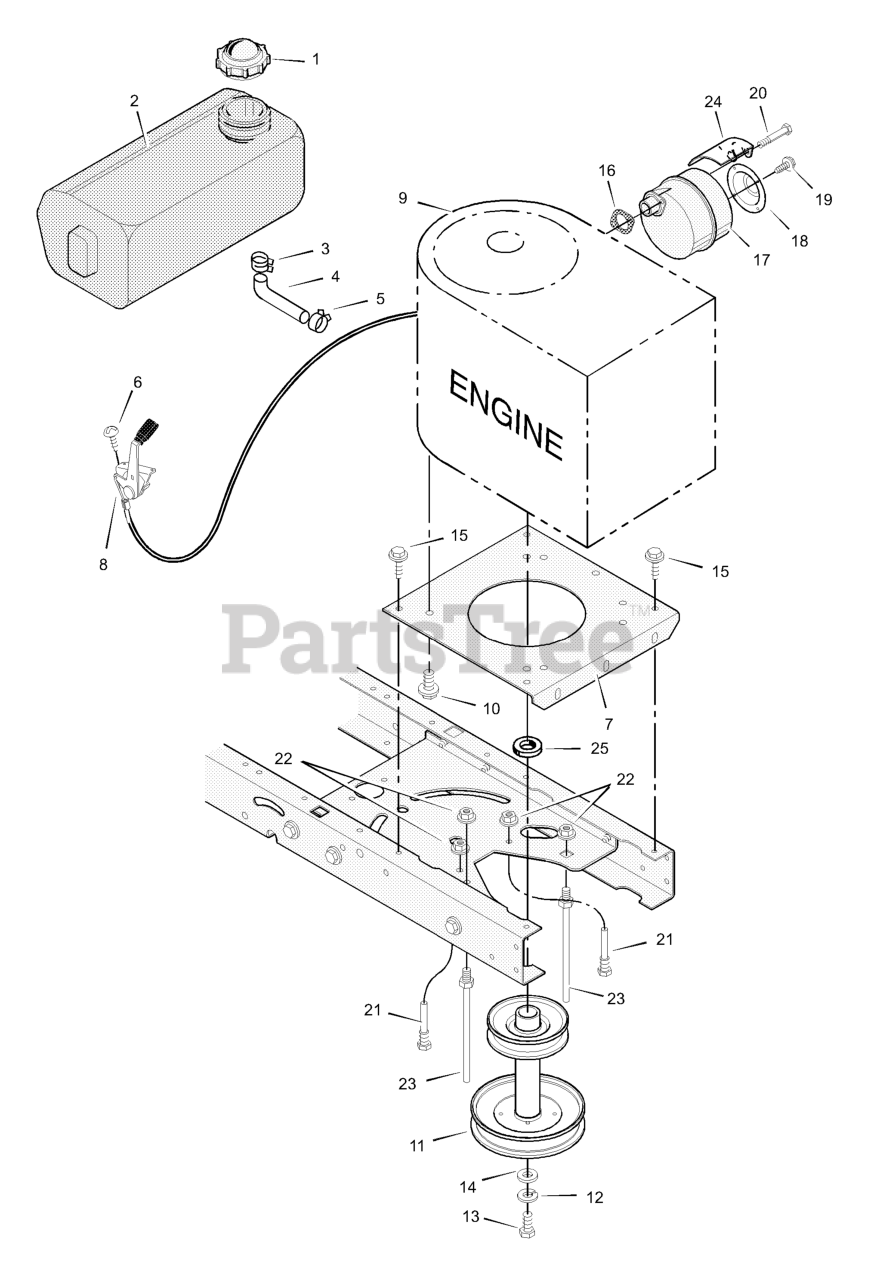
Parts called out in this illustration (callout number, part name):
1	Fuel Cap
2	Fuel Tank
3	Hose Clamp
4	Fuel Line (must cut to length)
5	Hose Clamp
7	Plate, Engine
8	Throttle Control
9	Engine
10	Bolt, Engine Mount
11	STACK PULLEY ASSEMBLY
12	Lockwasher
13	Bolt, Hex
16	GASKET, Exhaust
17	Muffler
18	Deflector, Muffler
20	Bolt, Hex
21	Guide, Belt
22	Nut, Flange
23	Guide, Belt
24	Shield, Heat
